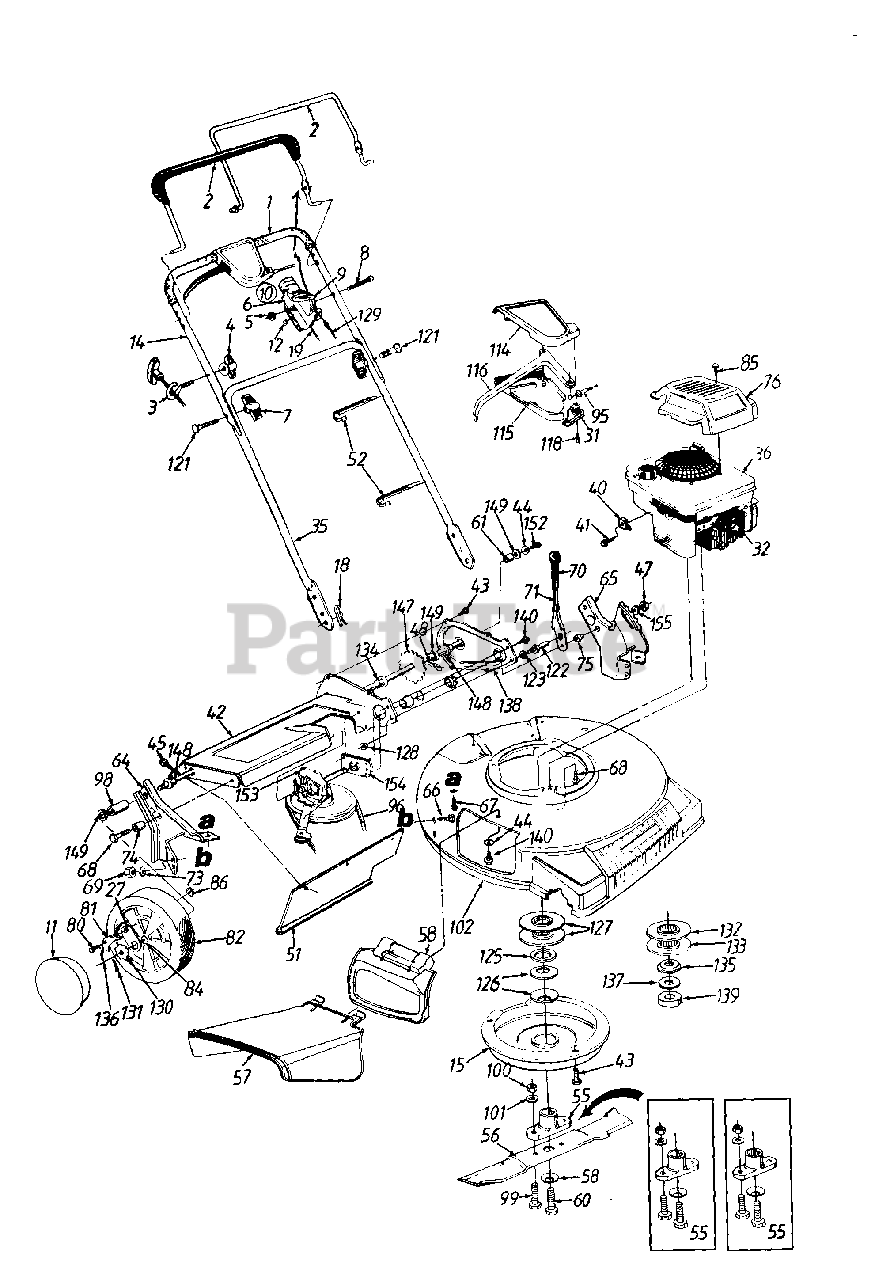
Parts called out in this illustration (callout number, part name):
1	Grip
2	Control Handle w/Plastic
3	Rope Guide
4	Handle Knob 1/4-20 Thd.
5	Hex L-Nut 1/4-20 Thd.
6	Throttle Body
7	Hand Knob
8	Oval C-Sunk Scr.
9	Throttle Lever
10	Throttle Box Comp.
11	5-1/2" Dia. Gray Hub Cap
11	3-1/2" Dia. Gray Hub Cap
12	Spr. Wash .66" I.D.
19	Throttle Control Wire 55" Lg.
19	Throttle Control Wire 42" Lg.
27	Pawl Plate
31	S.P. Control Cover
32	Spark Plug Insulator
36	Engine
40	Cable Clamp (B&S)
41	Hex Self-Tap Scr. #10-32 x .62" (B&S)
44	Bell-Wash. 1/4" I.D.
45	Hex AB-Tap Scr. 1/4 x .62"
47	Hex Patch L-Nut 3/8-24 Thd.
48	#48 Chain .500" Pitch x 38 Links
51	Rear Flap 4.8" x 17.5" Lg.
52	Cable Tie
55	Blade Adapter Kit (Splined)
55	Blade Adapter Kit (Keyed)
56	21" Mulching Blade
57	Chute Ass'y.
58	Mulching Plug Ass'y.
58	Bell-Wash..47" I.D.
58	Bell-Wash..39" I.D.
60	Hex Bolt 7/16-20 x 2.5"
60	Hex Bolt 3/8-24 x 2.5"
61	Spacer .513" I.D.
63	L-Wash. 5/16" I.D.
64	R.H. Handle Wheel Brkt. Ass'y.
65	L.H. Handle Wheel Brkt. Ass'y.
66	Carriage Bolt 5/16-18 x .62"
67	Hex B-Tap Scr. 5/16-18
68	Hex TT-Tap Scr. 3/8-16
69	Hex Nut 5/16-18 Thd.
71	Height Adj. Lever
73	Bell-Wash. 5/16" I.D.
74	Spacer .383" I.D.
75	Shld. Spacer .5" Dia.
76	XTE Black Shroud
76	Black Shroud
80	Shld. Scr..342" Dia. x .268
81	Pawl
81	RH Pawl
82	8" x 1.75", Wheel, Bar Tread
82	8" x 2" Gray, Wheel, "S" Wave
84	Sleeve Bearing 1/2" I.D.
85	Hi-Lo Scr. #10 x 1.25" Lg.
86	Weld Top L-Nut 1/4-20 Thd.
95	S.P. Cable - 44" Lg.
96	V"-Belt
98	Sleeve .526" I.D.
99	Hex Bolt 3/8-24 x 1.0" Lg.
100	Hex Nut 3/8-24 Thd.
101	L-Wash. 3/8" I.D.
115	Self-Propelled Control Cover
116	Control Lever
118	Fl-"C"-Sunk Hd. Tap Scr. #10 x 75" Lg
121	Curved Hd Bolt 5/16-18 x 2" Lg.
122	Shld. Pin 1.43" Lg.
123	L-Wash. 3/8" I.D.
125	Crankshaft Spacer
125	Serrated Wash. 1" I.D. (Tec.)
126	Bell-Wash 1.01" I.D.
126	Wave Wash. 1" I.D. (Tecumseh)
127	Pulley Half - 2 Req'd.
128	Hex Jam Nut 3/8-24 Thd.
129	Control Cable - 39"
129	Control Cable 51" Lg.
130	Ratchet Wheel 1.62" O.D.
131	Cotter Pin 1/8" Dia. x 1"
132	Pulley Half
133	Pulley Half
134	Hex Flange Bearing
135	Spr. Wash .89" I.D.
136	Spring - Nylon
137	Fl-Wash 85" I D
140	Hex S-Tap Scr. 1/4-20 x .50"
147	Rear Shaft Ass'y. 21.44" Lg.
148	Hex Flange Brg .506" I.D.
149	Fl-Wash .531" I.D. x .930"
152	Hex Bolt 1/4-20 x 62" Lg. (Grade 5)
153	Transmission Comp
155	Fl-Wash 385" I.D. x 87" O.D.
